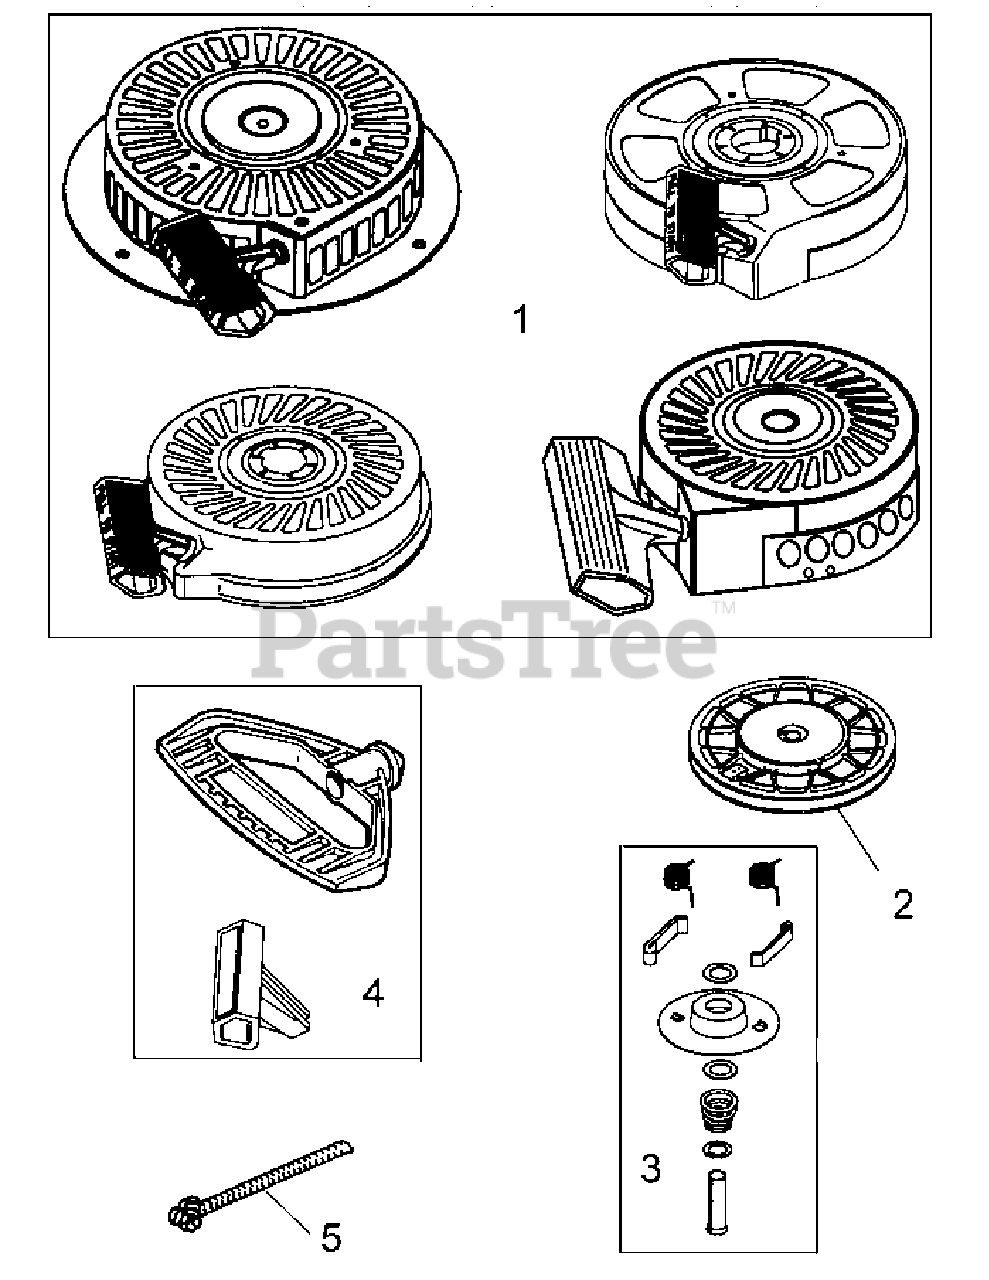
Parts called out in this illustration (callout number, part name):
1	Rewind Starter
2	Pulley & Rewind Spring Assembly
3	Repair Kit
4	Starter Handle
5	98" Starter Rope (cut to length)
